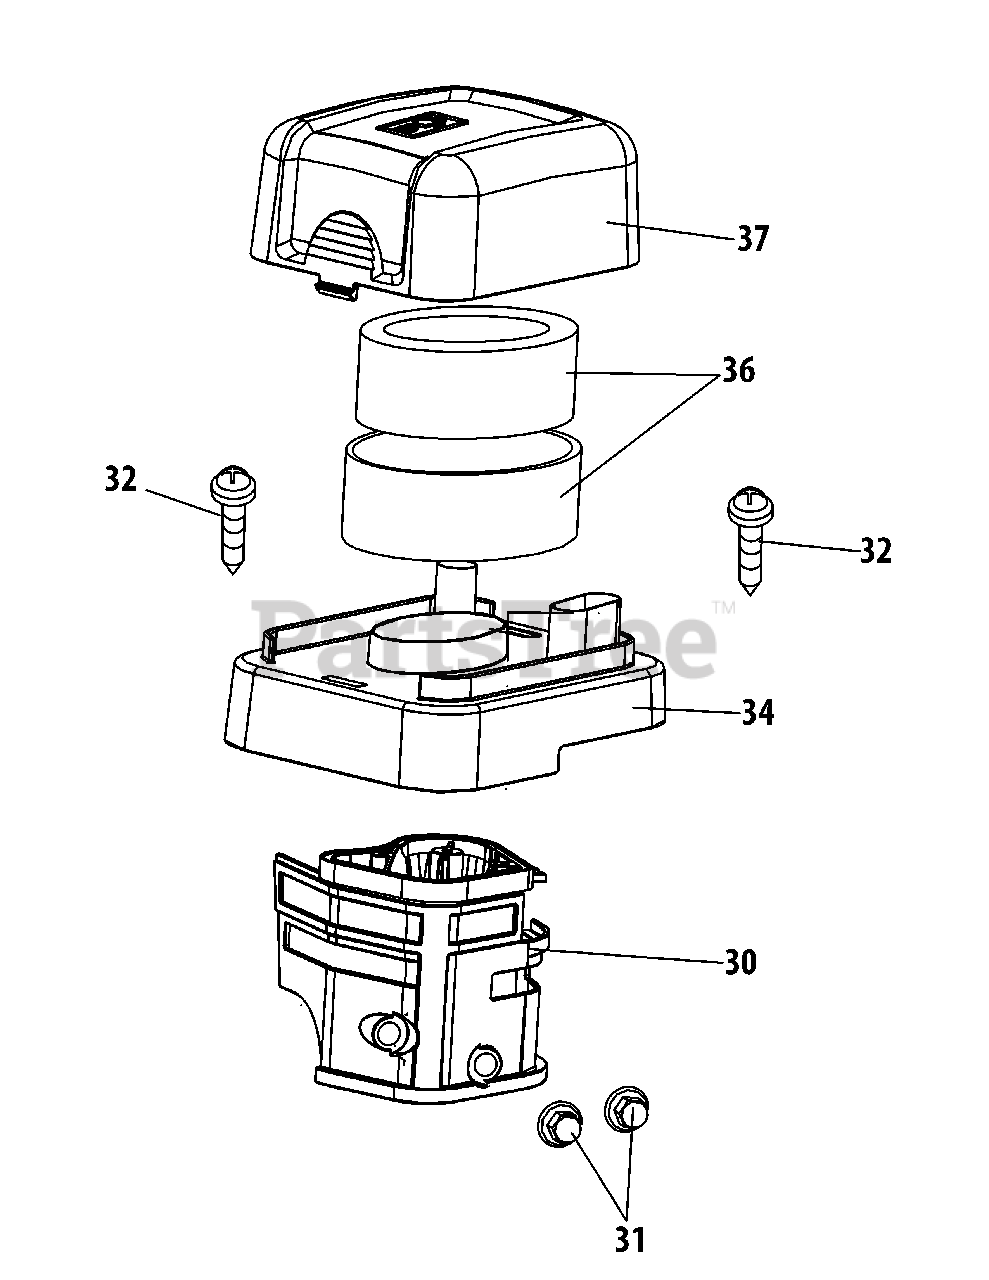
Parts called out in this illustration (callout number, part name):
30	Air Cleaner Housing
32	Self-Tapping Bolt M4.2×16
34	Housing - Air Filter Base
35	Sponge Filter
36	Air Cleaner Filter Assembly
37	Air Cleaner Cover
